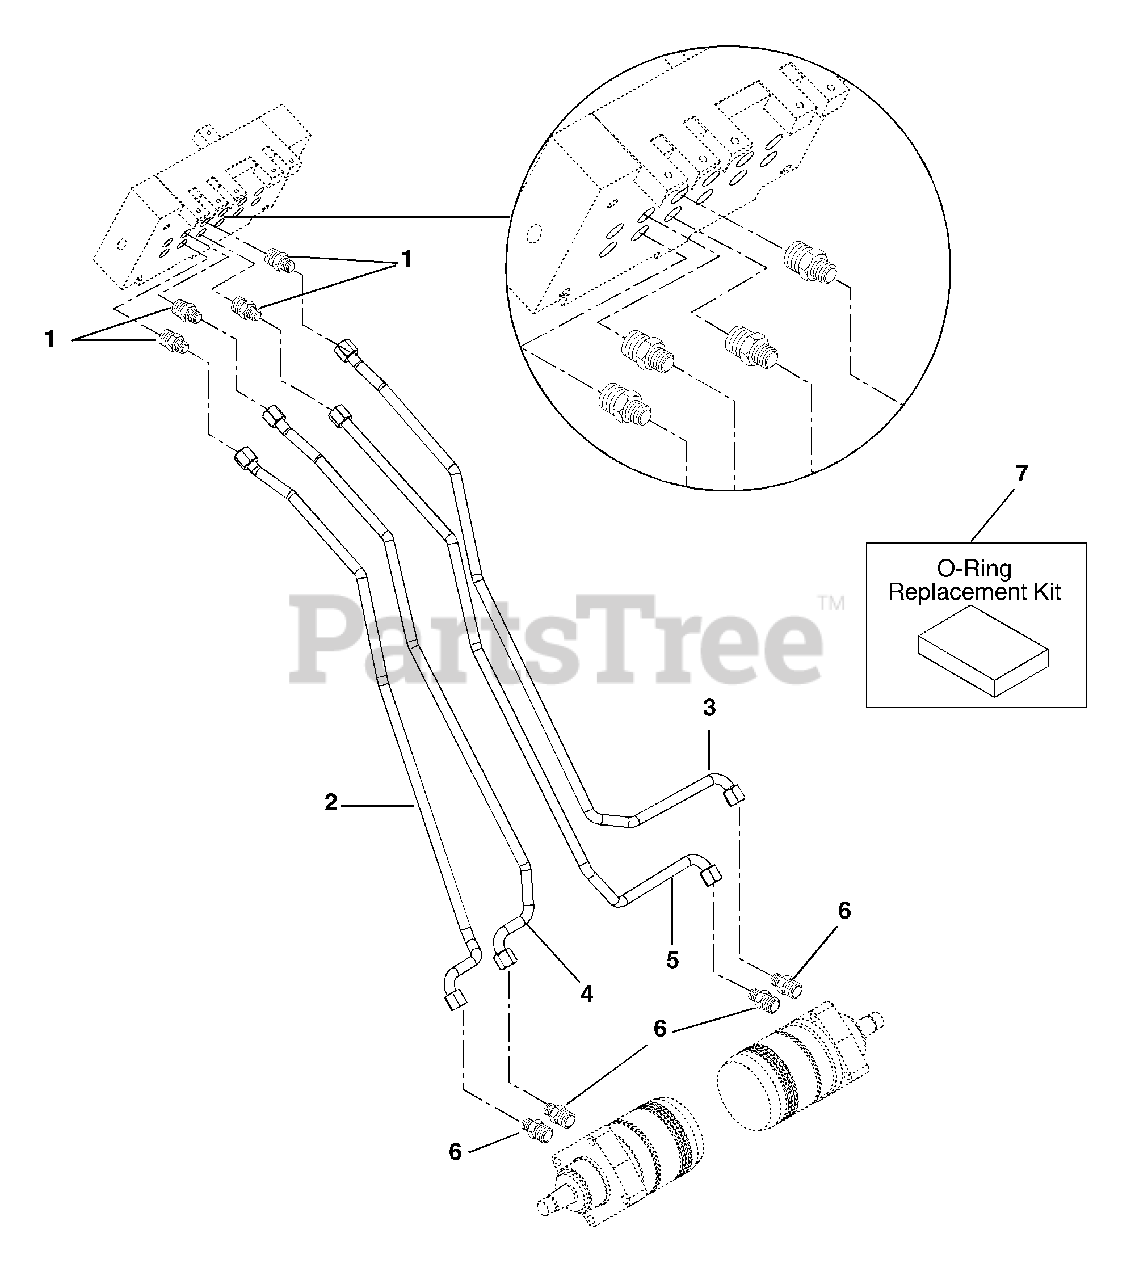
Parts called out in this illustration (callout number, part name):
1	Fitting, Hydraulic Straight
2	Tube, Right Hand Motor
3	Tube, Left Hand Motor
4	Tube, Right Hand Motor
5	Tube, Left Hand Motor
6	Fitting, Hydraulic Straight
7	Assorted O-Rings
